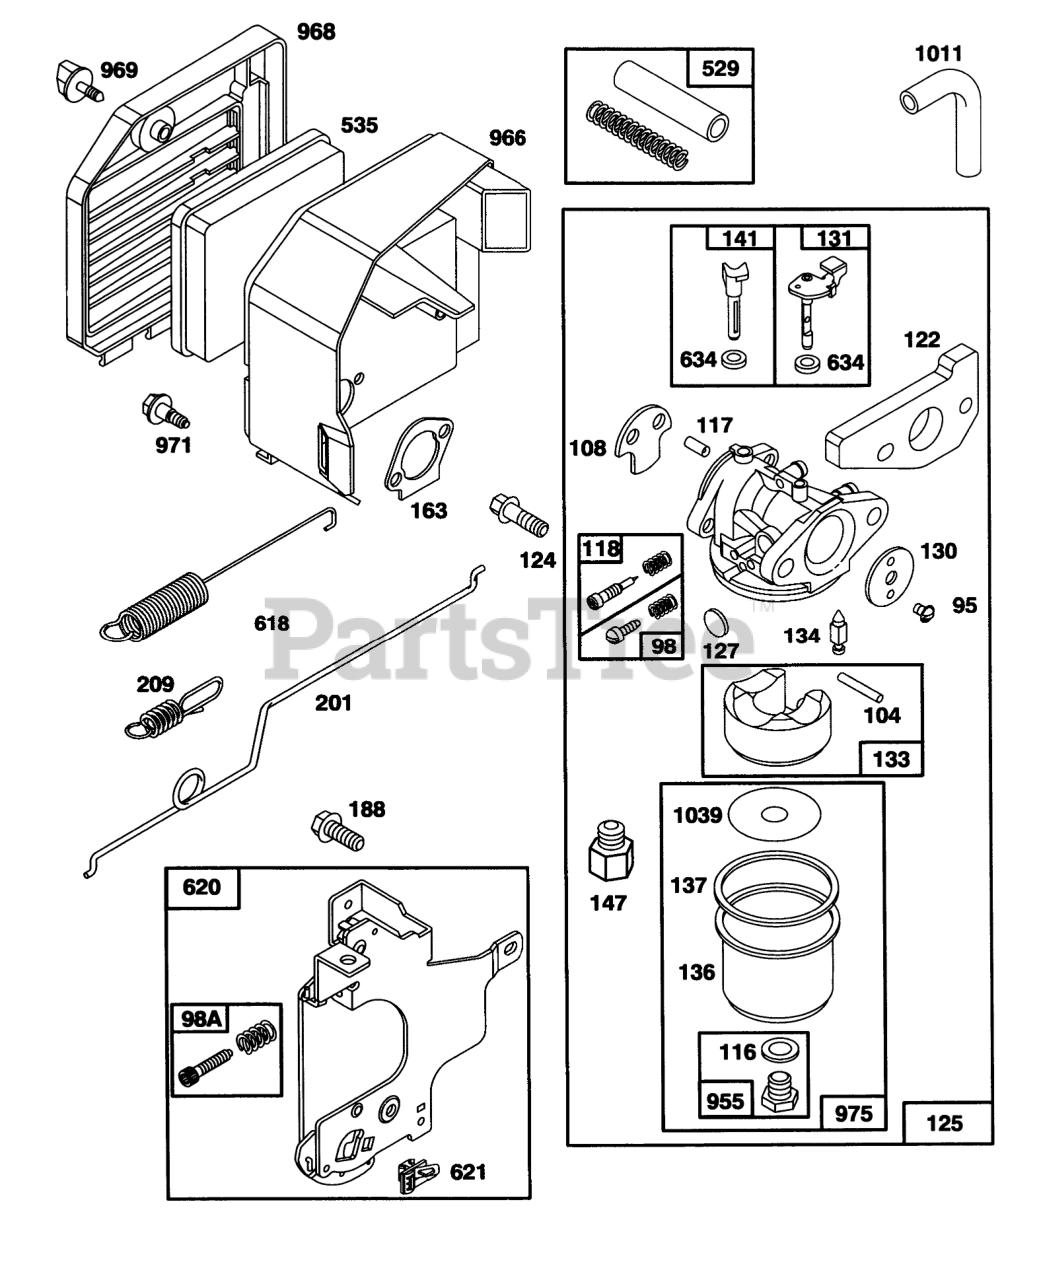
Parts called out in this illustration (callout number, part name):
95	SCREW - ROUND HEAD
98	IDLE ADJUSTING SCREW
98A	SPEED ADJUST. SCREW ASM
104	FLOAT HINGE PIN
108	CHOKE VALVE
116	SEALING GASKET
117	JET
118	VALVE KIT - NEEDLE
122	ADAPTER ASSEMBLY
124	HEX HEAD SCREW
125	CARBURETOR ASSEMBLY
127	PLUG
130	THROTTLE VALVE
131	THROTTLE SHAFT
133	FLOAT-CARBURETOR
134	Valve-Float (Includes Seat)
136	FLOAT BOWL
137	SCREW - HEX HEAD
141	CHOKE SHAFT
147	JET ADAPTER
163	AIR CLEANER GASKET
188	Screw-Cap
201	GOVERNOR LINK
209	GOVERNOR SPRING
358	GASKET SET
529	BREATHER TUBE
535	FILTER ELEMENT
618	RETURN SPRING
620	CARBURETOR BRACKET
621	STOP SWITCH
634	SEAL WASHER
955	HEX HEAD SCREW
966	AIR CLEANER BASE
968	AIR CLEANER COVER
969	AIR CLEANER SCREW
971	AIR CLEANER SCREW
975	CARBURETOR BOWL ASM
1011	VENT TUBE
1039	FLOAT LIMITER
